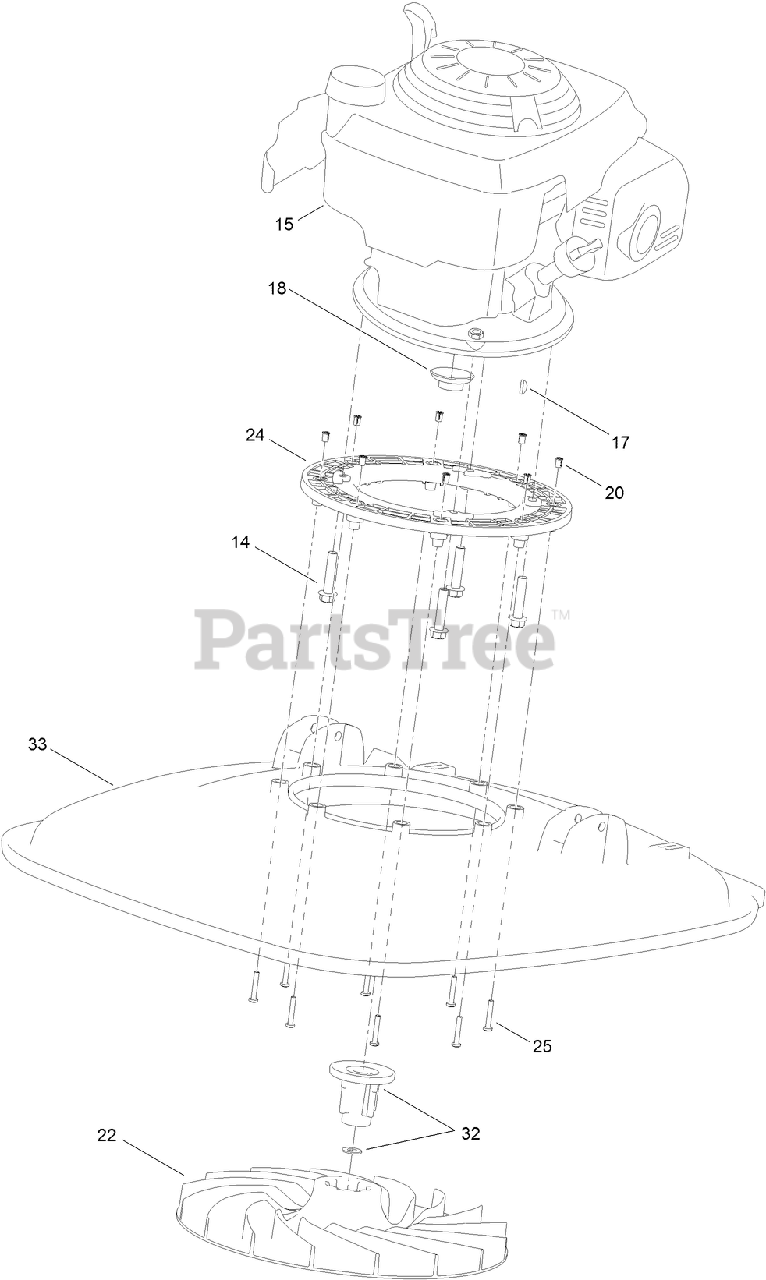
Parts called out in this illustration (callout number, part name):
14	SCREW-TAPTITE
17	KEY-WOODRUFF
18	PROTECTOR-SEAL, OIL
20	INSERT-BRASS
22	IMPELLER
25	SET-SCREW
32	DRIVE AND SPACER ASM
33	DECK-DRILLED
